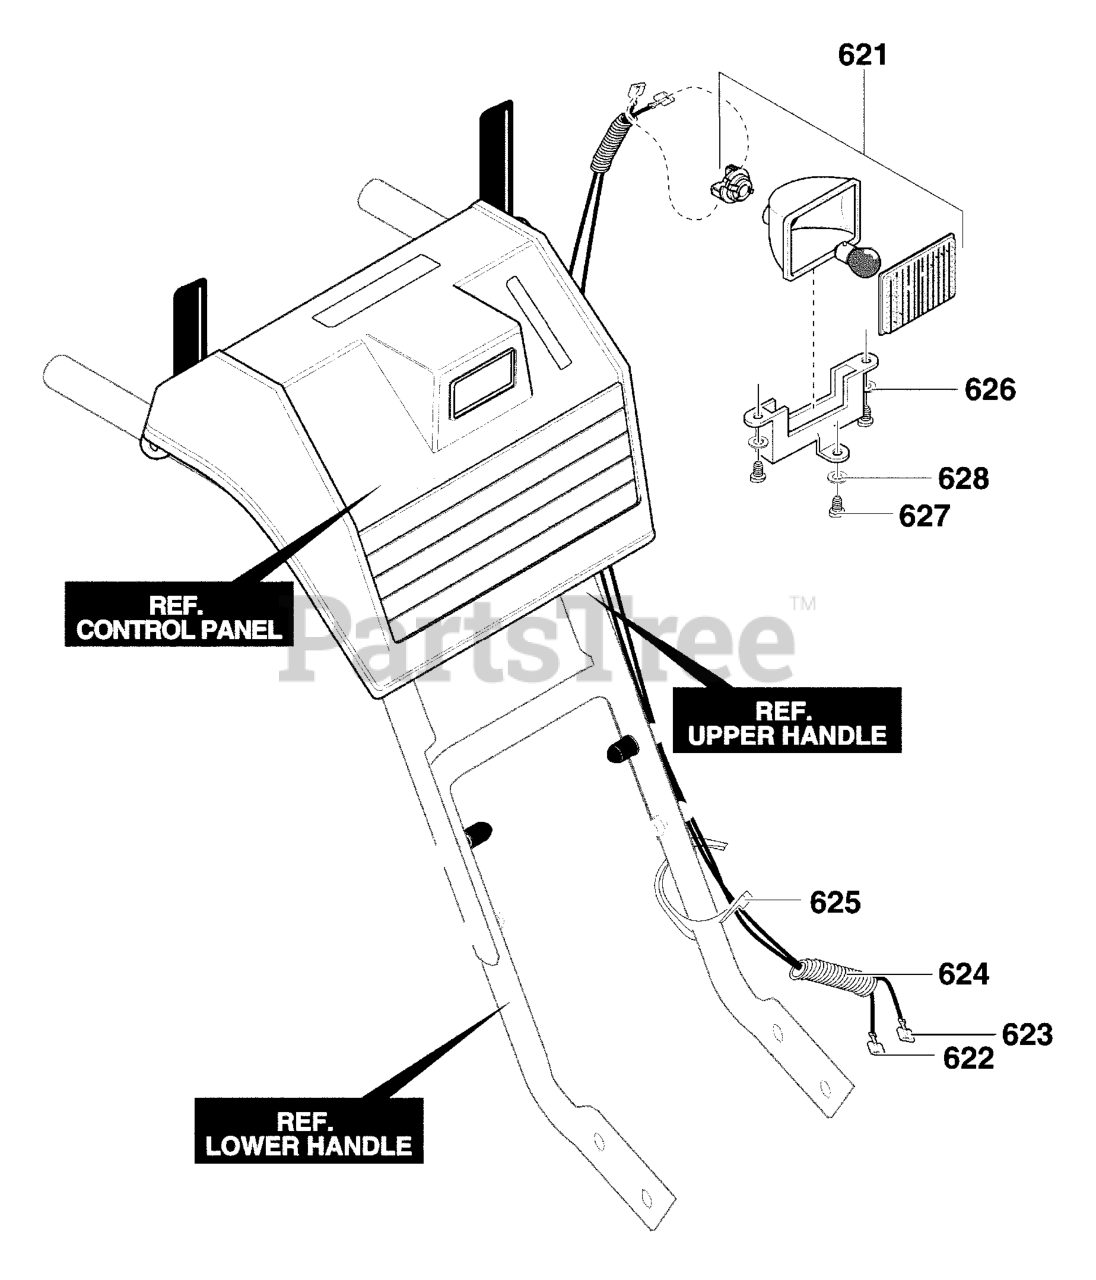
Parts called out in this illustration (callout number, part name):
621	HEADLIGHT ASSY
622	ASSY, WIRE
623	WIRE, HEADLIGHT GROUND
624	CONDUIT
625	TIE, CABLE
626	BRACKET
627	SCREW #8 X .50
628	WASHER, FLAT
